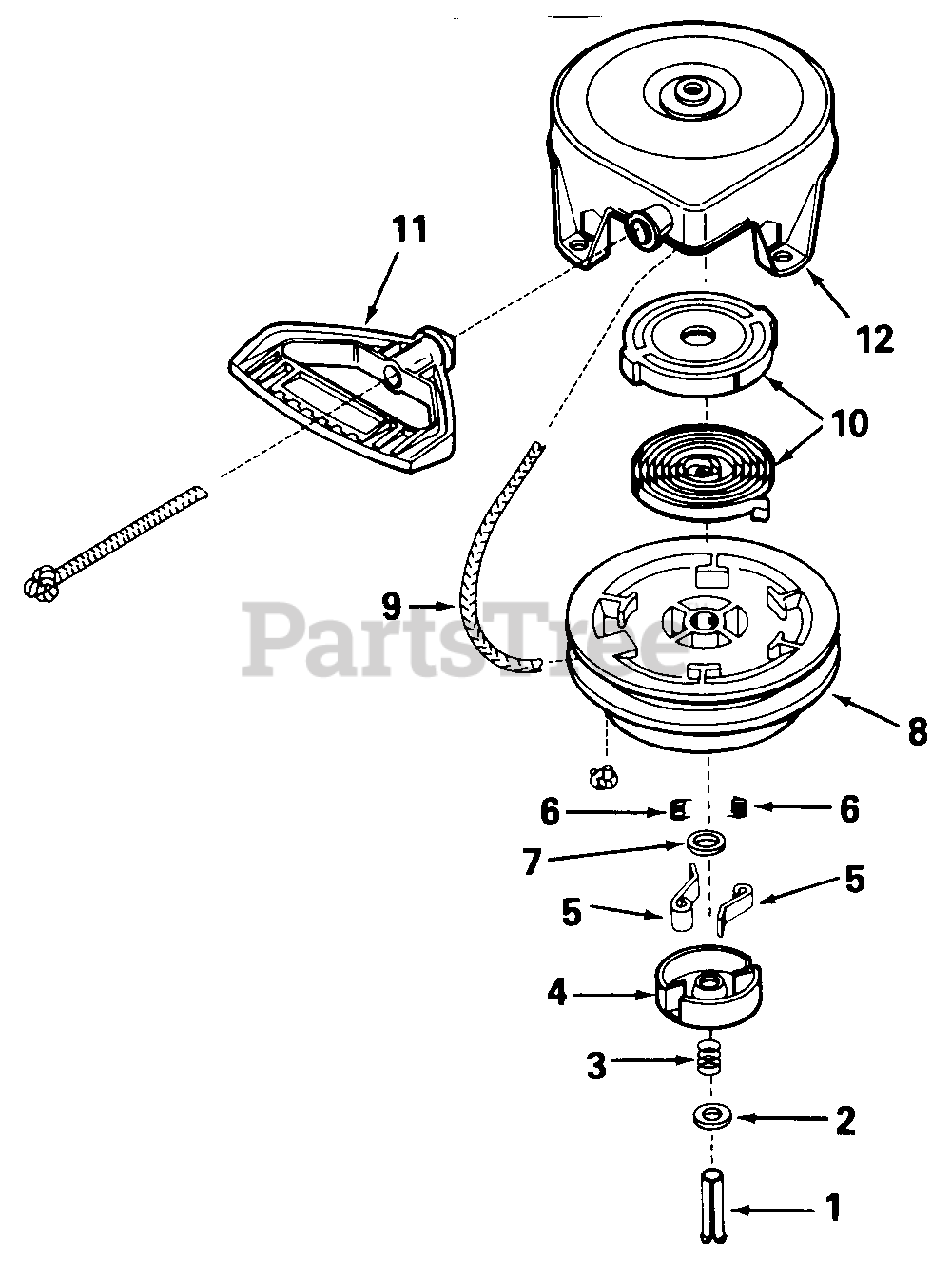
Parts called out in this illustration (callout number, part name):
1	Pin, Spring
3	Spring, Brake
5	Dog, Starter
6	Spring, Dog
9	Rope, Starter
10	Spring & Keeper Ass'y.
11	Handle, Mitten Grip (Not Included with Starter)
12	Housing Ass'y., Starter
